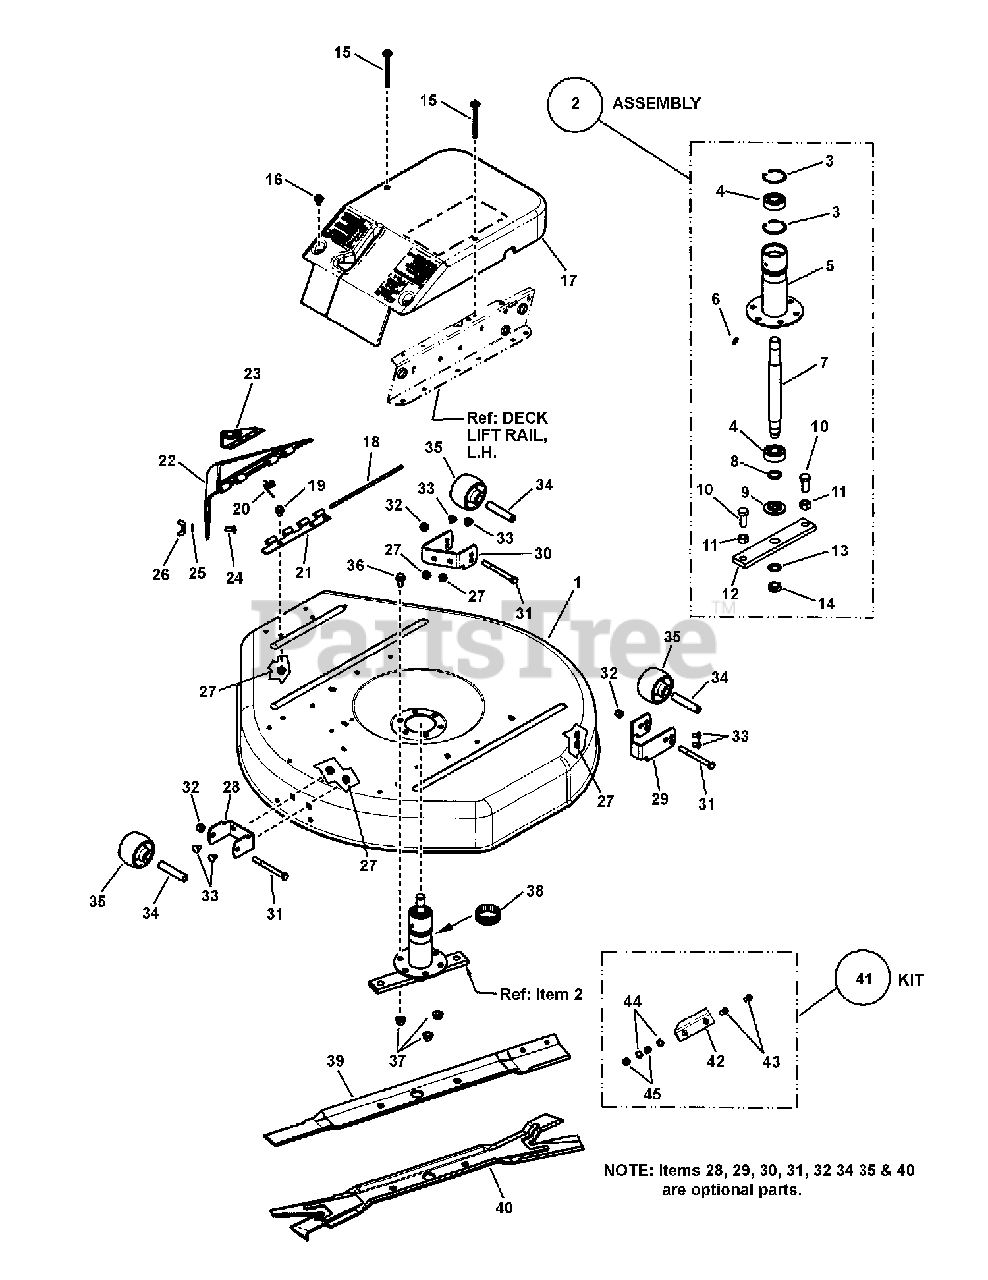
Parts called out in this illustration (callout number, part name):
1	DECK, 30" Replacement (Painted deck with decals)
2	KIT, Spindle Assembly
3	RING, 1.85" Internal Retaining
4	BEARING, Spindle
5	WELDMENT, Spindle Housing (includes 7010817, grease fitting)
6	LUBE FITTING, 3/16" Press-In
7	SPINDLE, Rider (10.327" overall length)
8	WASHER, .77 x 1.13 x .06 Flat
9	WASHER, Spindle
10	SCREW, 1/2-20 x 1-1/4" Hex Head Cap, GR 5
11	NUT, 1/2-20 Hex, GR 5
12	HOLDER, Blade
13	SPACER, Blade Centering
14	NUT, 5/8-18 Hex Center Lock Jam
15	SCREW, 1/4-20 x 3-1/2" Hex Head w/Free Spinning Washer
16	SCREW, 1/4-20 x 5/8" Hex Head w/Free Spinning Washer
17	COVER, Spindle
18	PIN, Hinge 6mm x 8.875
19	BOLT, 5/16-18 x 5/8" Hex Flange Lock, GR 5
20	SPRING, Torsion, Deflector
21	HINGE HALF
22	DEFLECTOR, 30"
23	DECAL, Danger (Cut Finger)
24	BOLT, 5/16-18 x 3/4" Short Neck Carriage, GR 5
25	WASHER, 5/16" Flat
26	NUT, 5/16-18 Wing
27	NUT, 5/16-18 Hex Flange Lock, GR 5
28	* BRACKET, Front Anti-Scalp
29	* BRACKET, Anti-Scalp, 30" L.H. Rear
30	* BRACKET, Anti-Scalp, 30" R.H. Rear
31	* SCREW, 3/8-24 x 3-3/4" Hex Head Cap, GR 5
32	* NUT, 3/8-24 Hex Center Lock
33	BOLT, 5/16-18 x 1/2" Short Neck Carriage, GR 5
34	* SPACER, 3"
35	* WHEEL, Gage
36	BOLT, 3/8-16 x 3/4" Hex Flange Lock
37	NUT, 3/8-16 Hex Flange Lock
38	RING, Tolerance
39	BLADE, 30" LC
40	** BLADE, Ninja, 30"
41	KIT, Air Lift (Includes items 42 thru 45)
42	AIR-LIFT, (30" Deck)
43	SCREW, 5/16-24 x 11/16" Oval Head Machine
44	WASHER, 5/16" Internal Tooth Lock
45	NUT, 5/16-24
